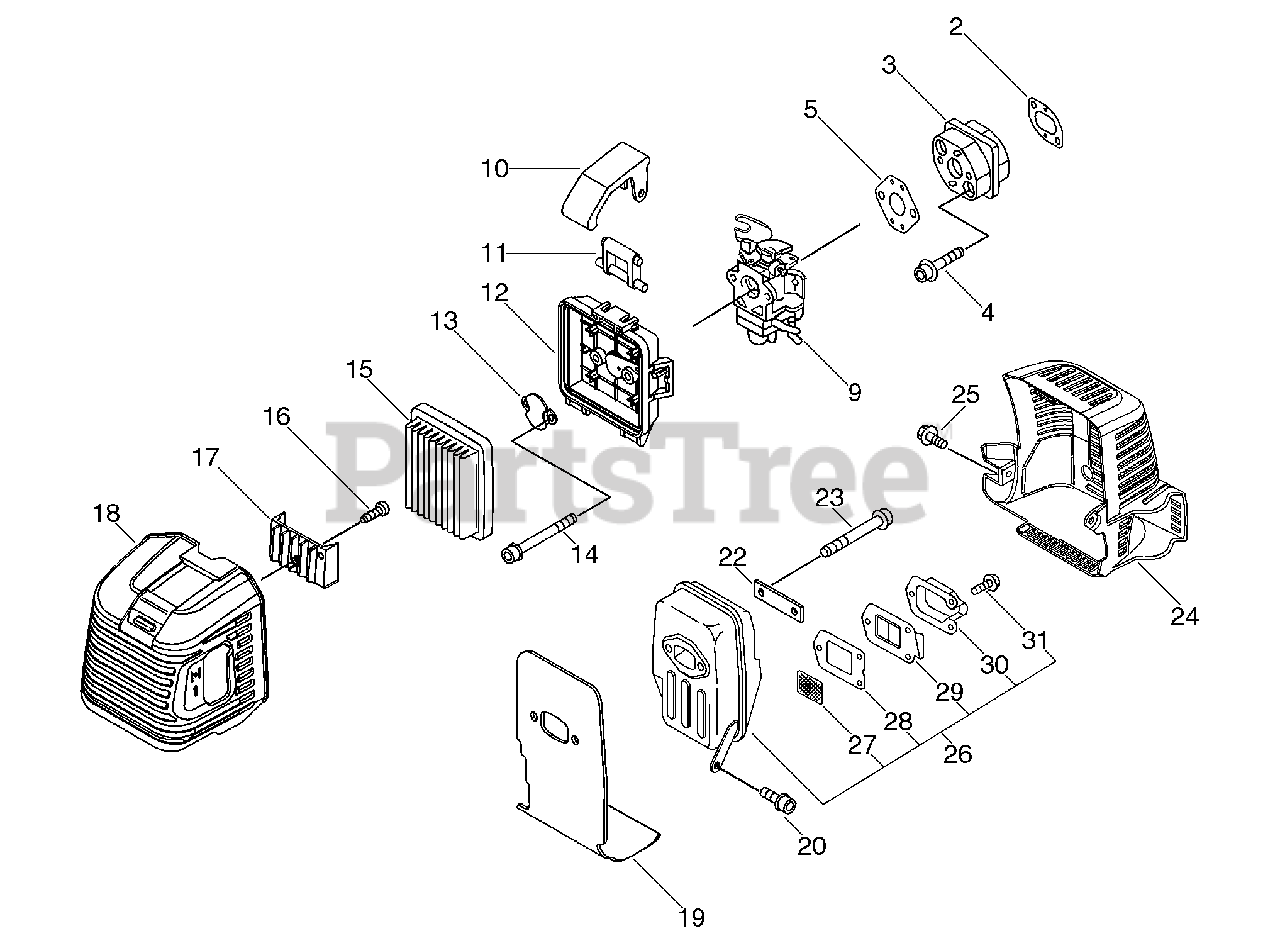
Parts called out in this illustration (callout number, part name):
2	GASKET, INTAKE
3	INSULATOR, INTAKE
4	SCREW - 5X25
5	GASKET, INTAKE
9	CARBURETOR
10	THUMBSCREW
12	CASE, AIR FILTER
13	PLATE, PREVENT
14	SCREW - 5X55
15	FILTER, AIR
16	SCREW - 4X8
17	PIECE,COVER
18	COVER, AIR FILTER
19	GASKET, EXHAUST
20	SCREW - 5X12
23	SCREW - 6X60
24	COVER, EXHAUST
25	SCREW - 5X12
26	MUFFLER ASSY
27	SCREEN, SPARK ARRESTOR
28	GASKET, EXHAUST
29	GUIDE, EXHAUST - INNER
30	GUIDE, EXHAUST - OUTER
31	SCREW - 4X10
